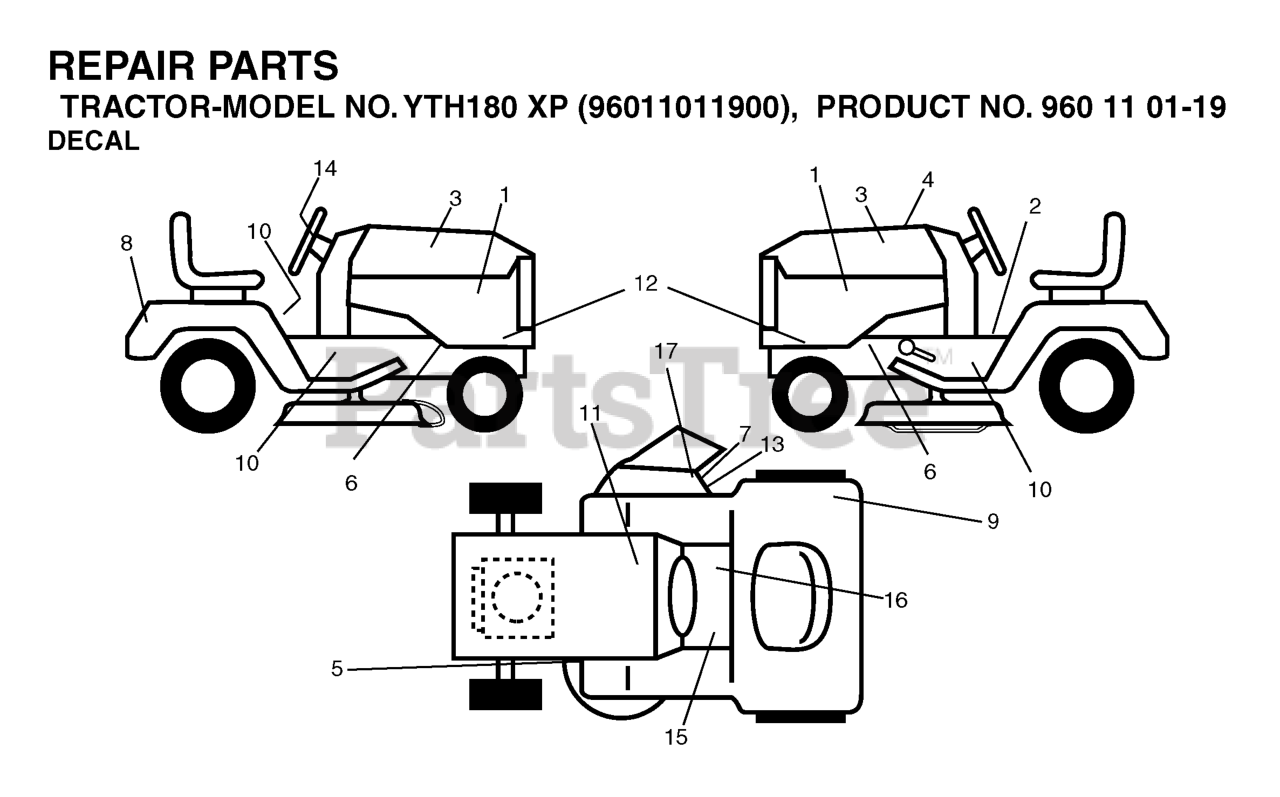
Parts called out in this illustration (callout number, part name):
1	DECAL.HOOD.HUSQVARNA.INTERNATI
2	DECAL PARK BRAKE
5	DECAL V BELT SCHEMATIC
7	DECAL.INTERNATIONL.CUTFINGER
9	Decal, Fender 100 DB/CE
11	DECAL BTRY SYMBOLS
13	DECAL, DEFLECT WARNING
14	DECAL.STEERING.HUSQ.BLUE
15	DECAL
16	LABEL
17	DECAL DECK "B" 42"
